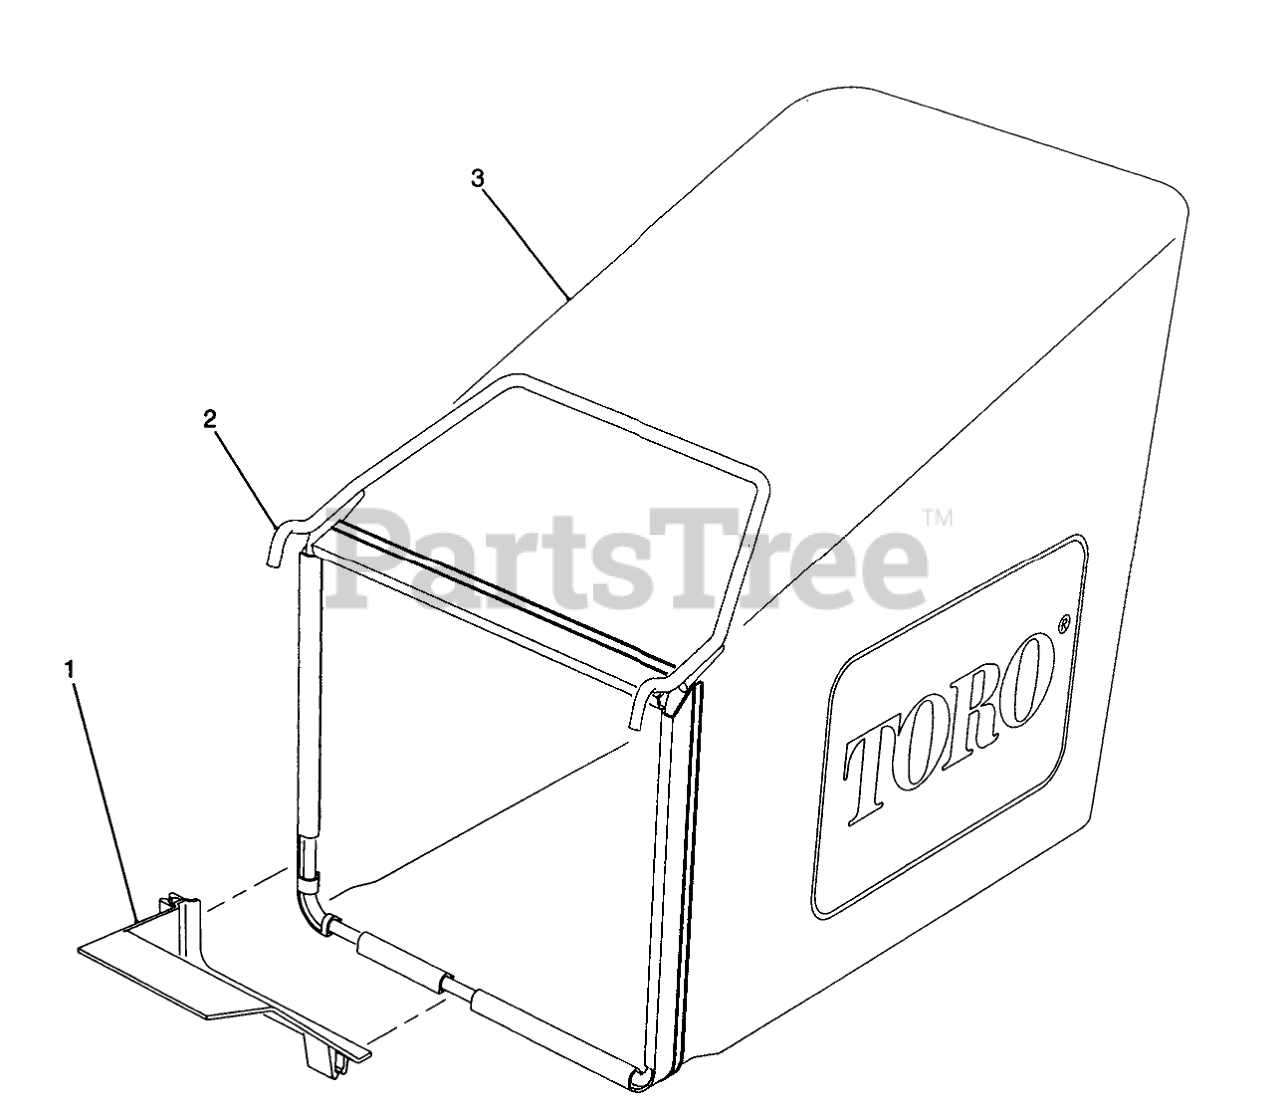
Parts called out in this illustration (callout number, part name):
1	BAG RAMP
2	Frame
3	GRASS BAG ASSEMBLY
